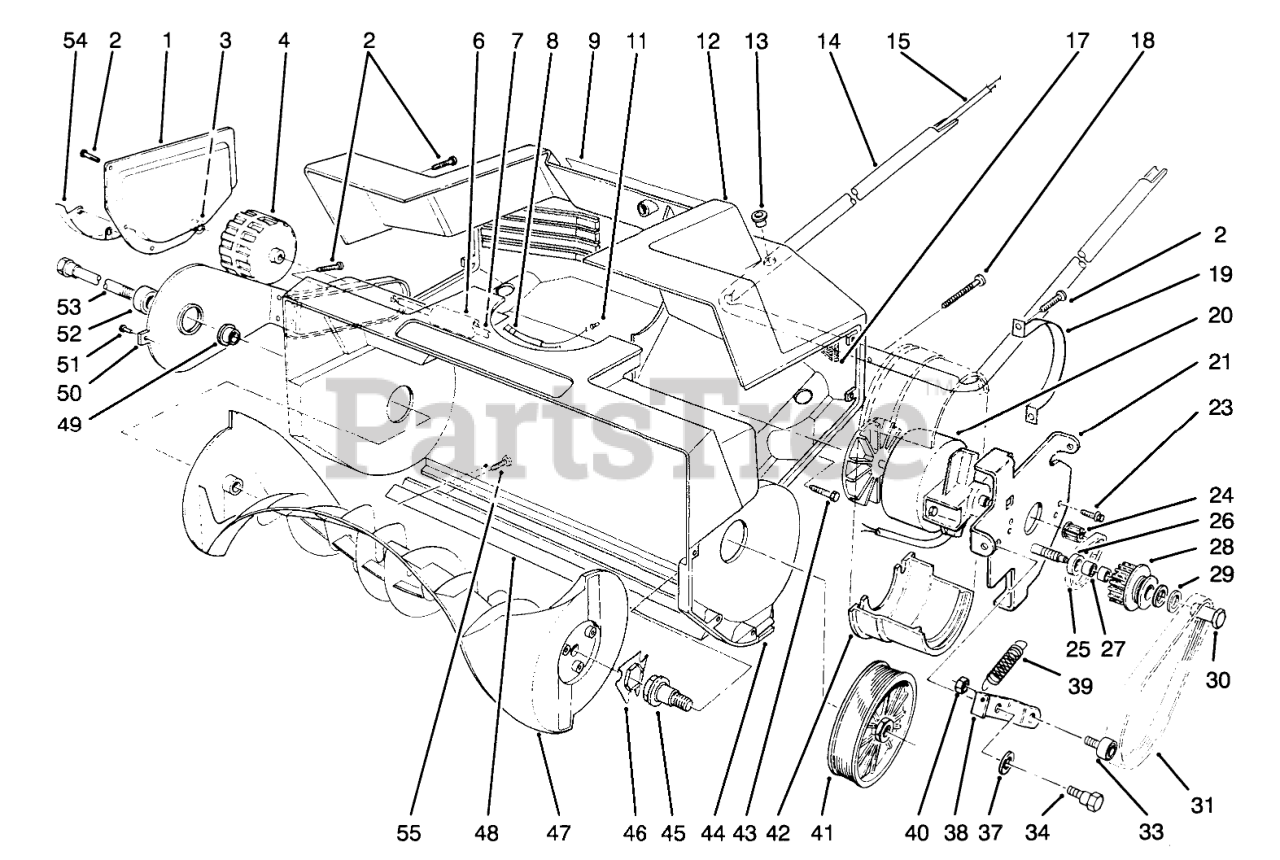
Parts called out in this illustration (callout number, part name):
1	Plate-Side
2	Screw
3	PUSHNUT-CAP, WASHER
4	Wheel
6	SLEEVE, AXLE
7	Shaft-Axle
8	Relief-Strain
9	Decal-Danger
11	Connector
12	Shroud-Housing
13	BUSHING
14	Tube-Lower Handle
15	Wire Harness
17	Filter-Foam
18	Screw-Pan Head
19	Strap-Motor
20	Motor
21	Motor Plate ASM
23	Screw-Hex Washer Hd.
24	Pulley-Driver
25	BELT-PULLEY, IDLER/DRIVER
26	WASHER
27	Bearing
28	Pulley Assembly-Idler (Incl. Ref. #27)
29	WASHER-THRUST
30	Bolt-Idler
31	Belt-Drive
33	Bearing Assembly (Incl. Ref. #40)
34	SCREW-SHOULDER
37	WASHER
38	Bracket-Idler
39	Spring
40	NUT-LOCK, NI
41	Pulley-Driven
42	Clamp-Motor Bracket
43	SCREW-HH
44	Housing-Rotor
45	Shaft-Driver, Rotor
46	Coupler-Rotor
47	Rotor
48	Scraper
49	BUSHING
50	Bracket-Wheel (Incl. Ref.#52)
51	RIVET-POP
52	Bearing-Ball
53	Shaft-Rotor
54	Skid-Housing
55	Screw-Pan Head
